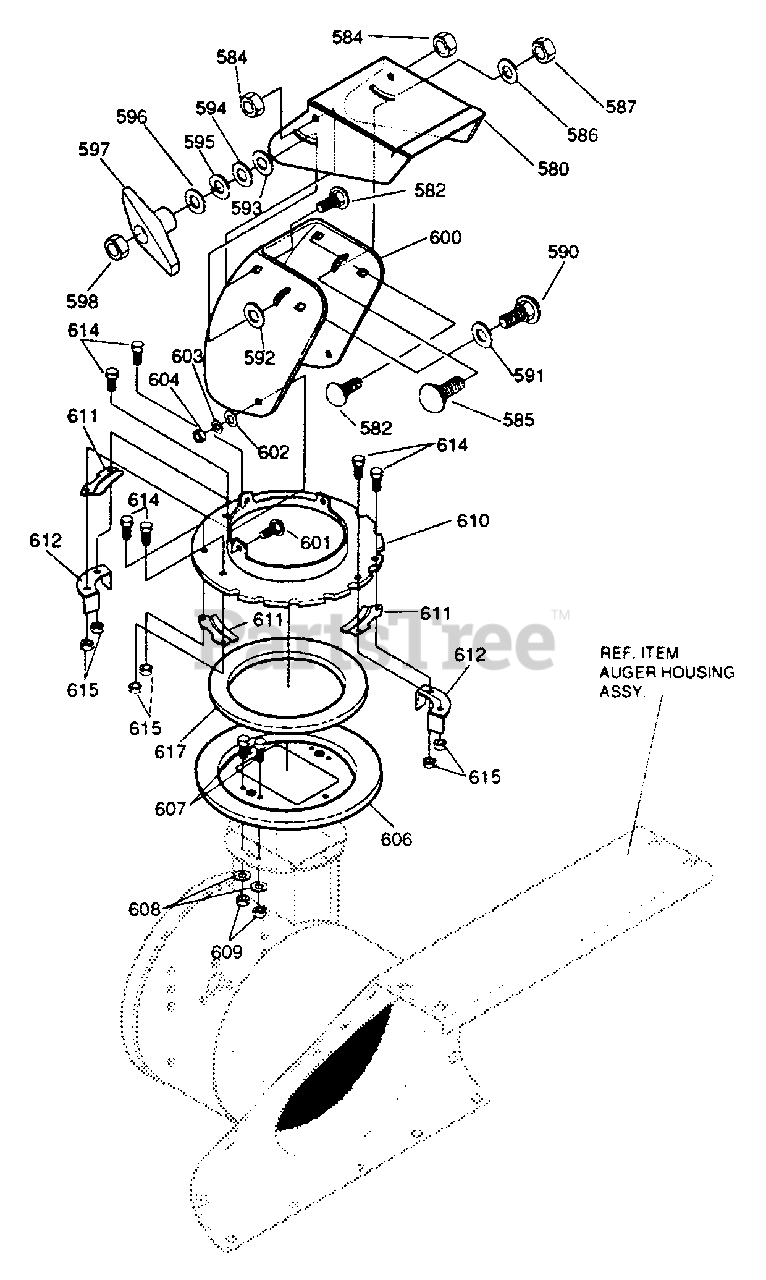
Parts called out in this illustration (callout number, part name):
580	CHUTE DEFLECTOR
582	SCREW, 5/16-18 x .75 SLTRMA
584	NUT, 5/16-18 HEXNYL
585	SCREW, 5/16-18 x .75 SLTRMA
586	PLASTIC WASHER, .315 x .75 x .064
587	NUT, 5/16-18 HEXNYL
590	CARRIAGE BOLT, 5/16-180.00
591	FLATWASHER, .469 x .92 x .065
592	FLATWASHER, .406 x .81 x .065
593	WASHER PLASTIC .315 x .75 x .064
594	FLATWASHER,.344 x .69 x .065
595	WASHER, HVSPTLK
596	FLATWASHER,.344 x .69 x .065
597	KNOB, T 2BLADE W-5/16-18 NUT
598	NUT, 5/16-18 REGHEX
600	CHUTE, LOWER
601	CARR. BOLT, 5/16-18 x .75
602	FLATWASHER, .344 x .69 x .065
603	WASHER, HVSPTLK
604	NUT, 5/16-18 REGHEX
606	COLLAR, CHUTE ADAPT
607	SCREW, 1/4-20 x .75
608	FLATWASHER, .281 x.63 x .065
609	NUT, 1/4-20 REGHEXCTRLK
610	FLANGE CHUTE
611	CLIP, CHUTE RET.
612	STOP, CHUTE LONG
614	SCREW, #8-32 x .50 WAHHMA
615	NUT, #8-32 HEXCTRLK
617	RING, FLANGED CHUTE ROT.
